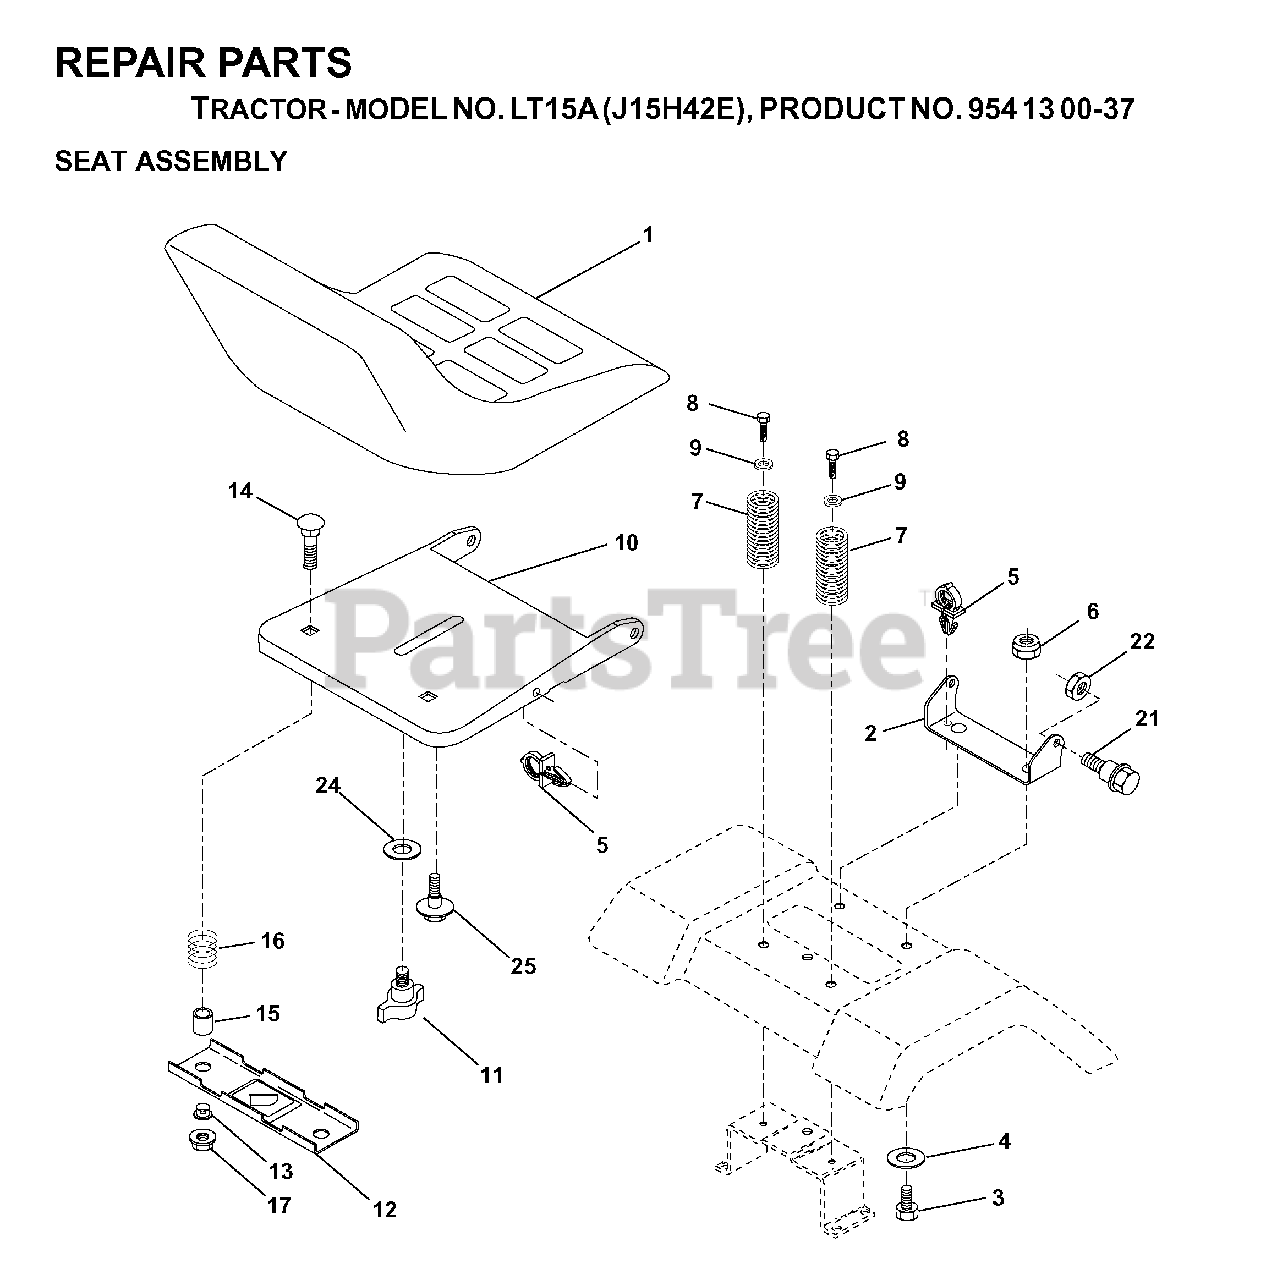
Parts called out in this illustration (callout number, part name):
2	SEAT PIVOT BRKT
4	WASHER PM
5	PUSH CLIP
6	NUT
7	SPRING COMPRESSION
8	SCREW 3/8-16X1
9	WASHER
10	PAN, SEAT
11	KNOB.SEAT.ADJ.WINGNUT
12	BRKT SWITCH
14	BOLT.ROUND.HEAD.SQUARE.NECK
15	SPACER SPLIT 28X.96
17	NUT T
21	BOLT.SHOULDER.5/16-18
22	NUT.71038.31-18.HEX.NYLOCK
25	BOLT,SHOULD
